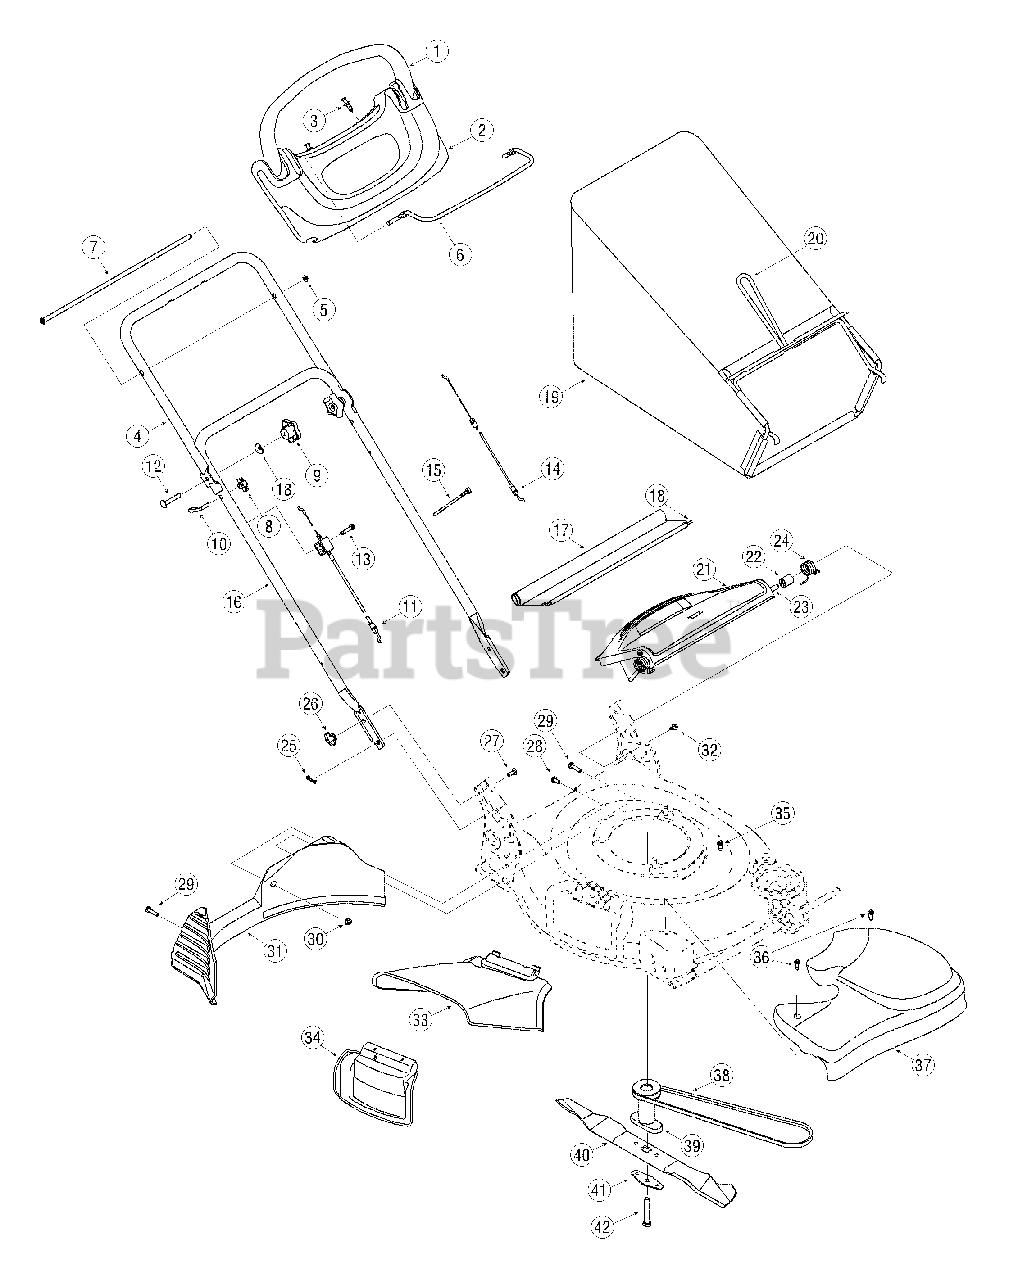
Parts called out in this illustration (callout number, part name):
1	Handle Assembly Comp.: Red
2	Handle Panel
3	Plastic Rivet
11	Fwd Drive Cable: Smart Speed (TM)
12	Carriage Bolt 5/16-18 x 2.0
13	TT Screw 1/4-20
14	Control Cable: Smart Speed (TM)
15	Cable Tie
17	Rear Trailing Shield
18	Wire
19	Grassbag Assembly
21	Rear Discharge Door
22	Spacer .375 x .50 x 1.02
24	Torsion Spring LH
26	Wing Nut
27	Carriage Bolt 1/4-20
28	Shoulder Screw 1/4-20
30	Flange Lock Nut 1/4-20
31	Rear Baffle 21" Rd.
32	TT Screw 1/4-20 x 0.5
33	Chute Deflector
34	Mulch Plug Comp.
35	Shoulder Screw 1/4-14
36	Shoulder Screw # 12 -24
37	Transmission Cover
38	V-Belt
39	Blade Adapter w/ Pulley
40	21" Mulching Blade
41	Blade Bell Support
42	Hex Screw 3/8-24 x 2.50
